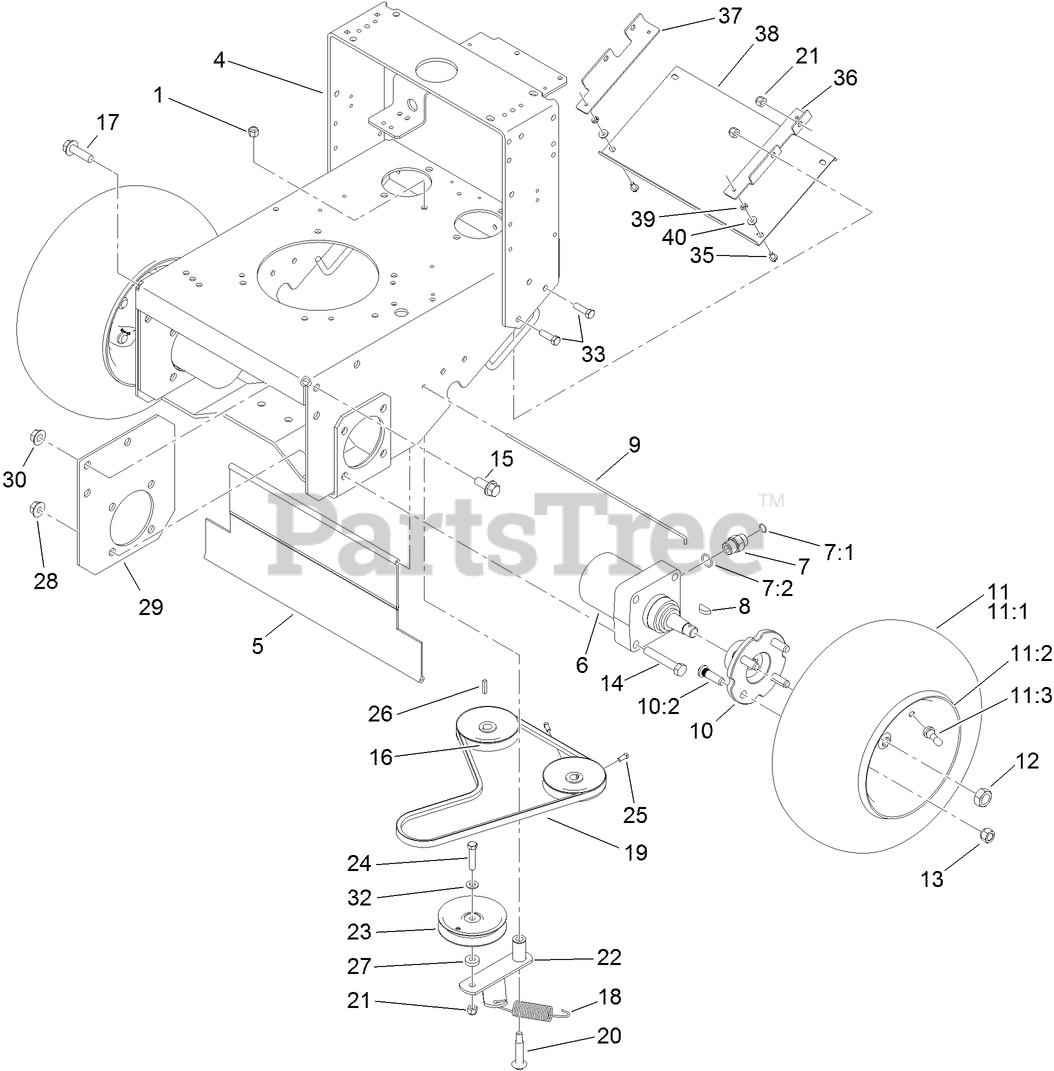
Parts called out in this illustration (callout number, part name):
1	NUT-LOCK
4	FRAME-HYDRO
5	SHIELD-TRAILING
6	HYD MOTOR ASM
7	FITTING-STRAIGHT
7:1	O-RING
7:2	O-RING
8	KEY-WOODRUFF
9	ROD-SHIELD
10	WHEEL HUB ASM
10:2	STUD-TYPE, DRIVE
11	WHEEL AND TIRE ASM
11:3	STEM-VALVE
12	NUT-MOTOR, WHEEL
13	NUT-LUG
14	SCREW-HH
15	SCREW-HHF
16	PULLEY-PUMP
17	SCREW-HHF
18	SPRING-TRACTION
19	BELT-V
20	BOLT-WHEEL
21	NUT-LOCK, NI
22	IDLER LEVER ASM
23	PULLEY-IDLER
24	SCREW-HH
25	SCREW-SET
27	Washer
28	NUT-HHF
29	PLATE-FRAME
30	NUT-HF
32	WASHER-FLAT
33	SCREW-HH
35	SCREW-HWH
36	ANGLE-MOUNTING, LEFT
37	ANGLE-MOUNTING, RIGHT
38	PANEL-BOTTOM
39	NUT-RETAINER
40	WASHER-FLAT
